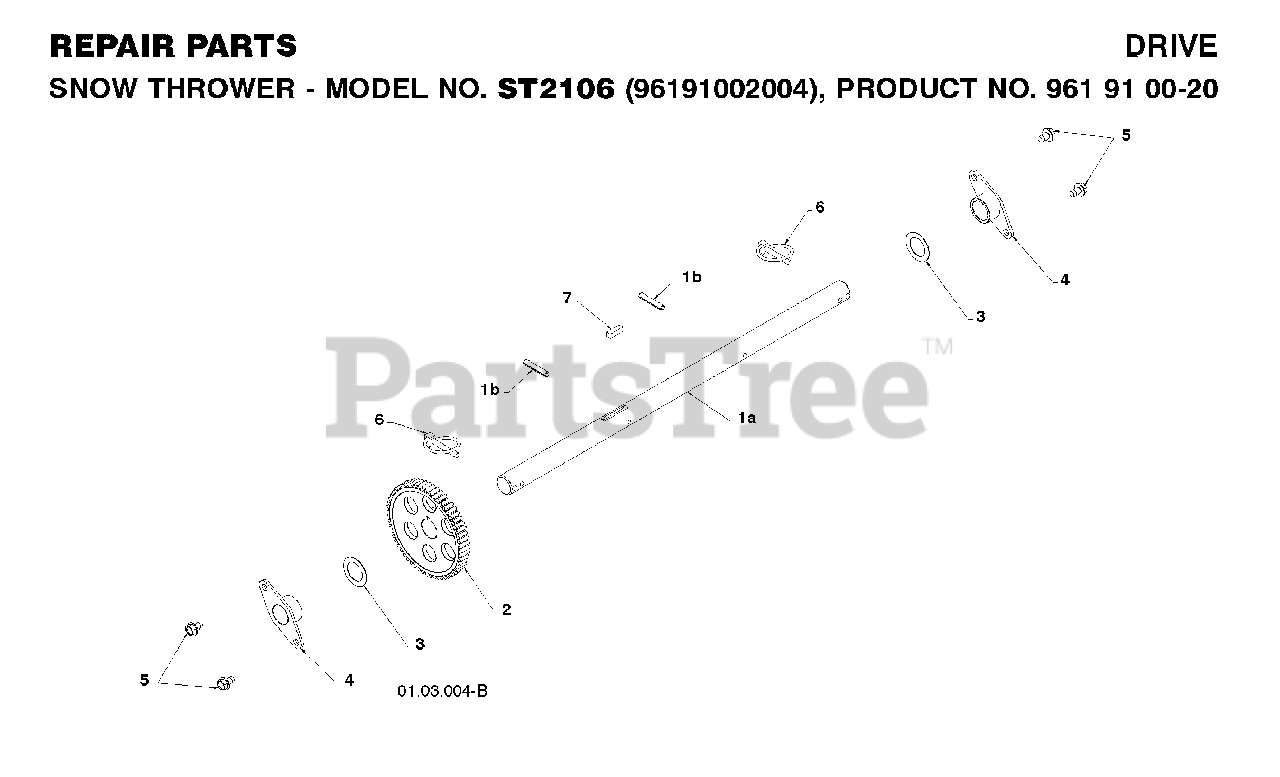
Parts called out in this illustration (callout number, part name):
1	AXLE.SHAFT.ASM.W/ROLPIN.
1A	SHAFT.AXLE.16".SNOW
1B	PIN.ROLL.3/16
2	GEAR, AXLE (58T)
3	WASHER TRUST 1"
4	BEARING, AXLE
6	PIN KLIK, 1/4
7	KEY, SQUARE 1/4 X .875
